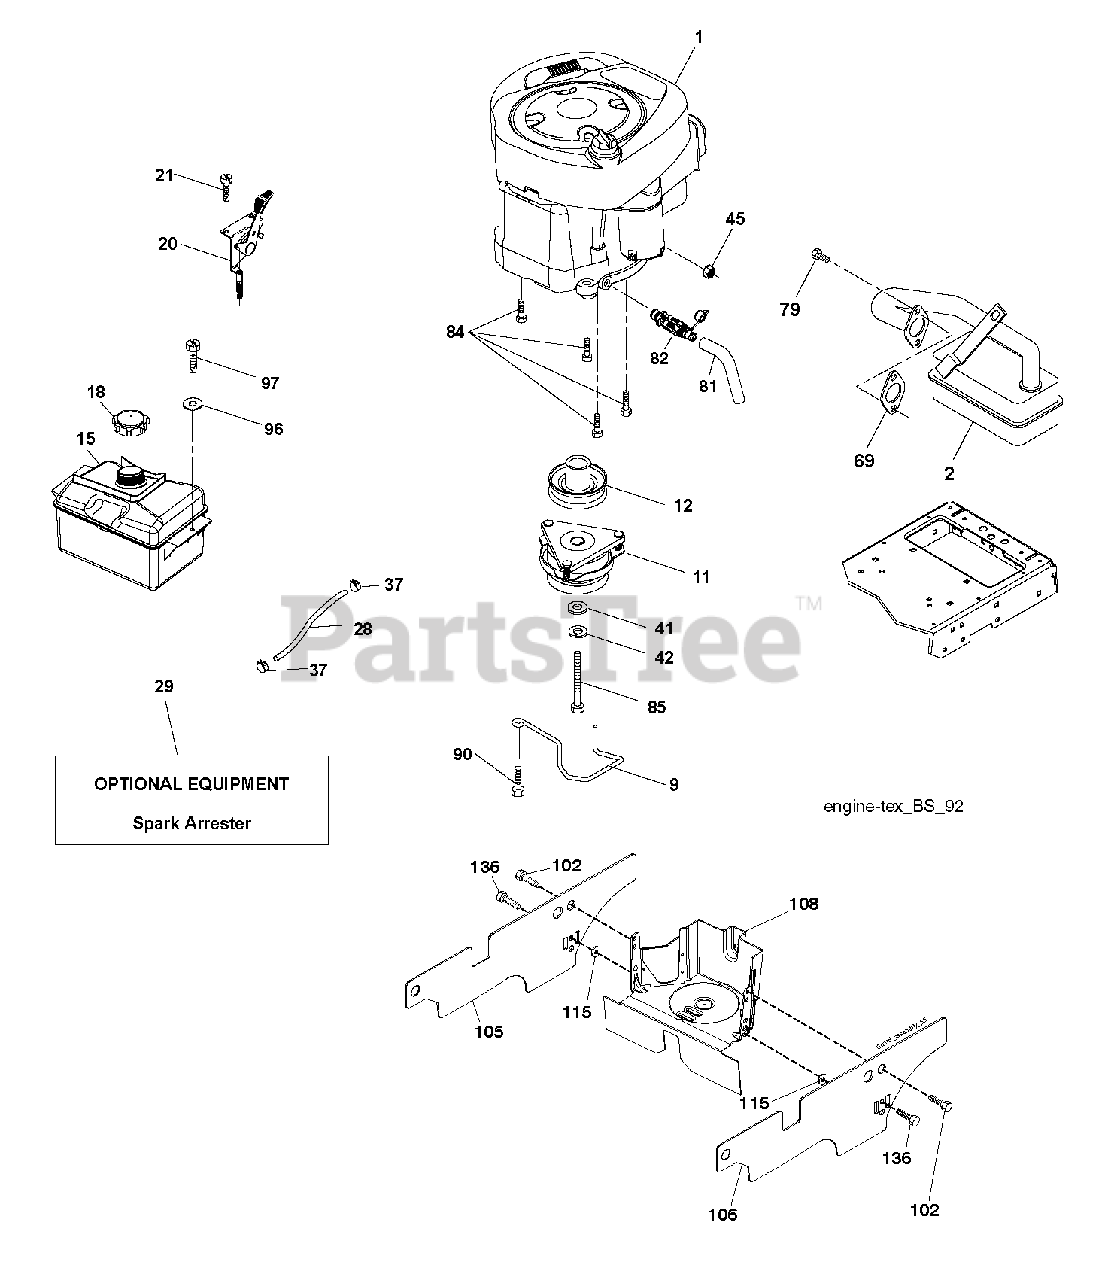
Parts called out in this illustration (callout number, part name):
2	MUFFLER.LT.BRIGGS.14HP.IC/OHV
9	KEEPER BELT ENGINE
11	RB.CLUTCH.OGURA.4.4.PD
12	PULLEY.ENGINE.TUFFTORQ
15	RP TANK FUEL FRT 1.5 GAL
18	CAP ASM.FUEL.2.25"FR.
20	CONTROL.TH/CK.C.
21	SCREW.#10 X 0.750.BOS
28	LINE.FUEL.20
29	KIT.SPARK ARRESTOR 794945 B&S
37	HOSE CLAMP
42	LOCKWASHER
45	NUT
69	REPL BY 532 27 22-93
79	SCREW.SOCKET HD.5/16-1
81	TUBE, DRAIN OIL ASM.
82	VALUE.OIL.DRAIN
84	SCREW.3/8-16
85	BOLT HEX 7/16-20X4-1/4"
90	SCREW 3/8-16X1
96	WASHER
97	SCREW HEXWSHR 1/4-20X3/4
102	SCREW
105	SHIELD.SIDE.LH.3842"TEX FRENCH
106	SHIELD.SIDE.RH.3842"TEX FRENCH
108	ENGINE COVER
115	PALNUT 1/4
136	SCREW.1/4-20X5/8
